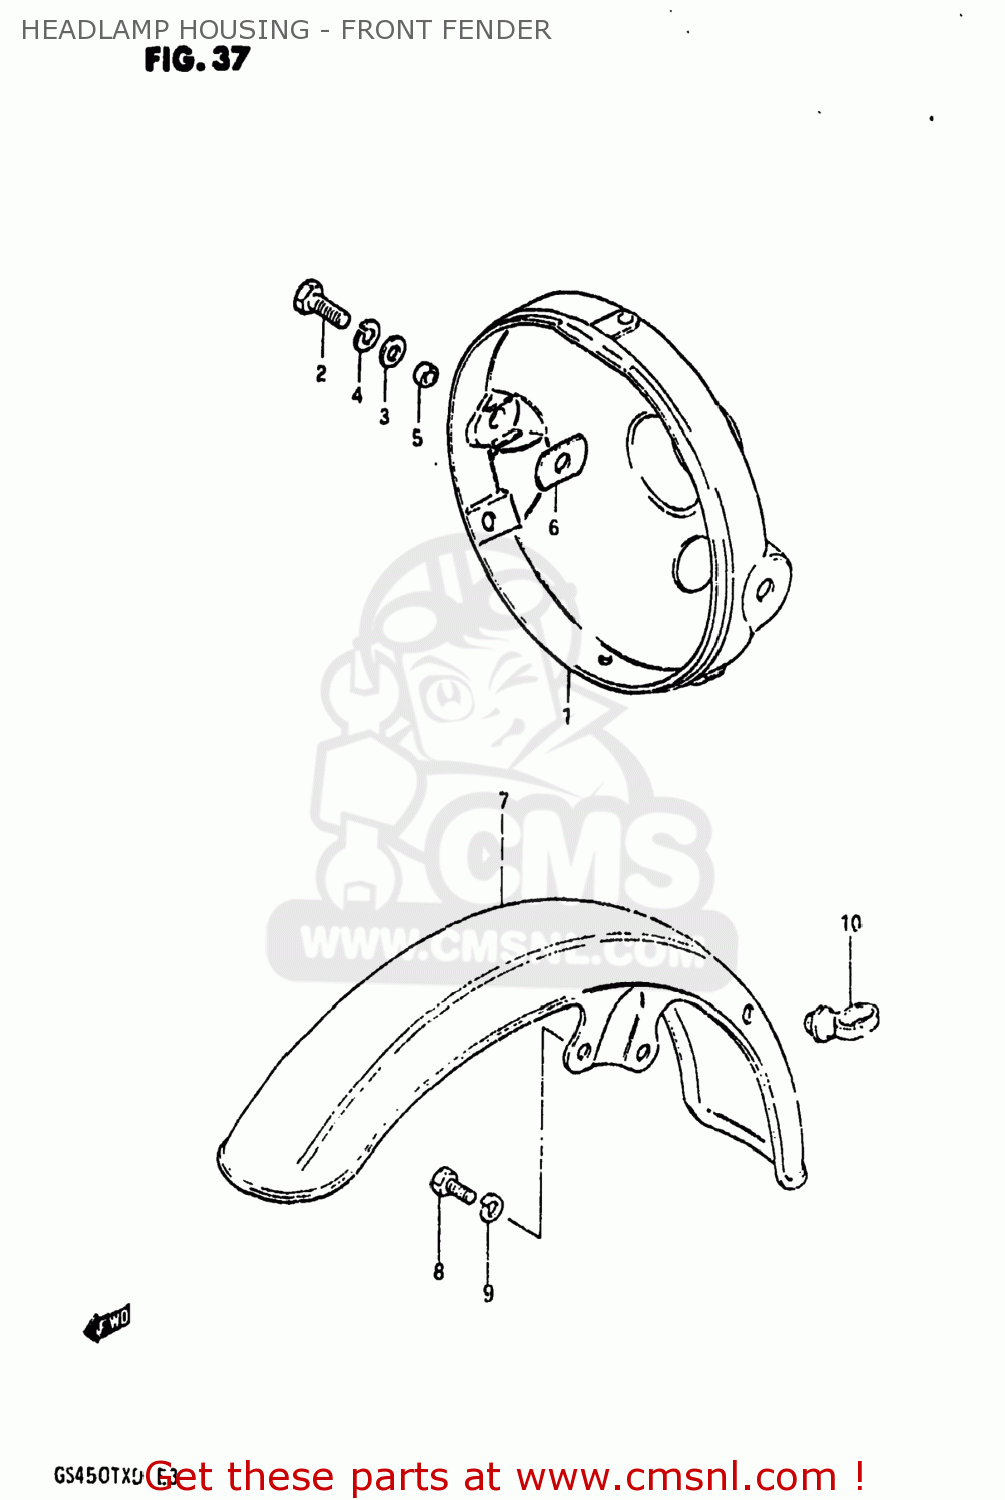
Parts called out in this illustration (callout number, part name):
1	HOUSING,HEADLAMP
2	BOLT
3	WASHER
4	LOCK WASHER
5	SPACER (8.8X12X7)
6	CUSHION
7	FENDER,FR
8	BOLT
9	LOCK WASHER
10	GUIDE,CABLE
